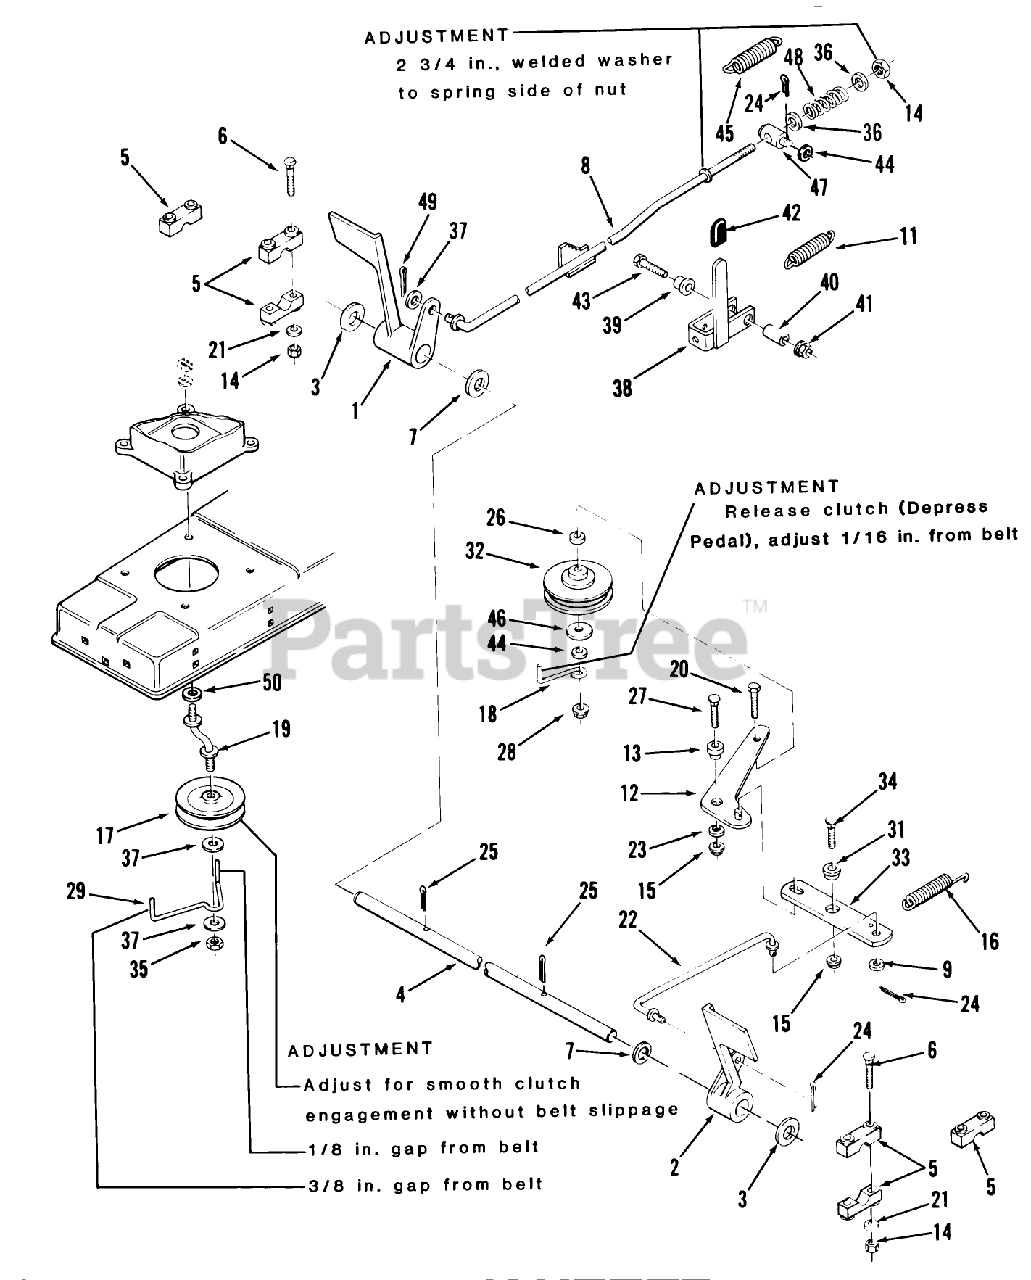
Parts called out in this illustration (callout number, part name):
1	PEDAL-BRAKE R
2	Pedal Clutch
3	WASHER-SPECIAL
4	SHAFT-PEDAL
5	BLOCK PIVOT
6	Washer
7	Washer
8	ASSY-BRAKE ROD
8	BRAKE ROD ASSY
9	WASHER 5/16 SAE
11	SPRING-EXTENSION
12	IDLER ARM ASSY R
13	SPACER-IDLER ARM
14	Nut
15	LOCKNUT-FLANGE
16	SPRING
17	PULLEY-IDLER STATION
18	RETAINER-BELT
20	Bolt
21	WASHER 5/16 SAE
22	ROD-CLUTCH R
23	Washer
24	Pop Rivet
26	SPACER
27	Carriage Bolt
28	LOCKNUT-FLANGE
29	RETAINER-BELT
31	SPACER
32	IDLER PULLEY
33	BAR-CLUTCH
34	Bolt
35	Nut
36	Collar
37	Washer
38	PAWL-HANDLE ASSY
39	SPACER
40	SPACER
41	LOCKNUT-FLANGE
42	GRIP
43	Bolt
44	Washer
45	SPRING-EXTENSION
46	WASHER
47	TRUNNION-LIFT
48	SPRING FRICTION
49	Cotter Pin
50	Washer-Lock
